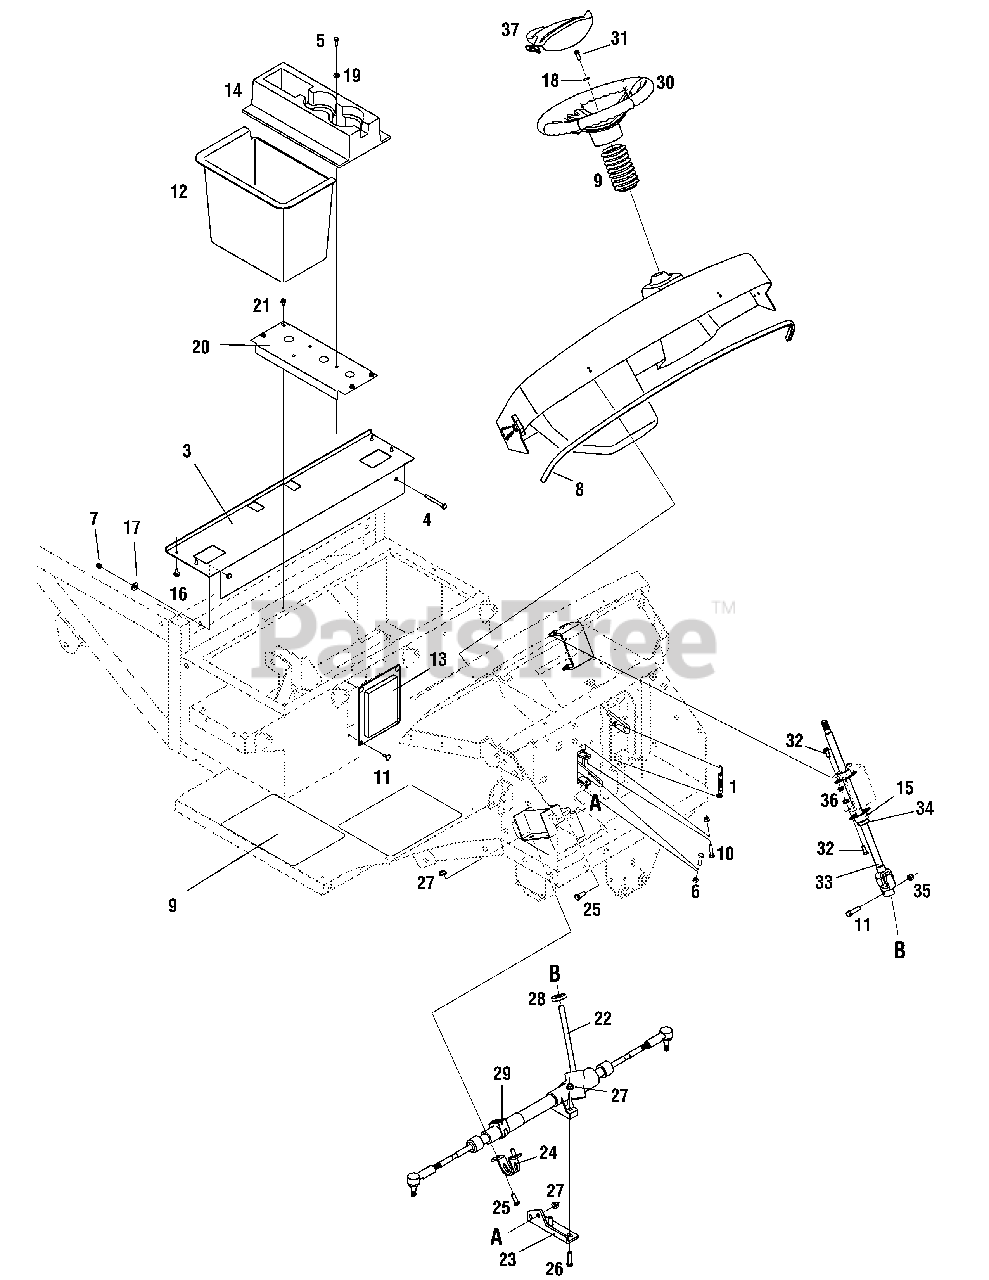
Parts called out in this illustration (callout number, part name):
1	Spring, Ext., .50 OD x 4.35 Lg.
2	Hood Mounting Plate
5	Tt Screw, 5/16-18 x .500
6	Nut, Hex, 5/16-18
7	Hex Lock Nut, Nylon, 5/16-18
8	Trim, Bulb Seal, 1/4
9	Bellow, Steering, 4.75 Lg
10	Screw, 5/16-18 x 1.25
11	Hex Screw, 3/8-16, 1.75, Gr5
12	Container, Bulkhead
13	Panel, Shift Cover
14	Console, Cup Holder
15	Brg, Flange, .75 ID, Self-Aligning
16	Bumper, Rubber
17	Washer, Flat, .349 x .879 x .063
18	Washer, Flat, .344 x .688 x .065
19	Washer, Flat, .39 x 1.38 x .062
22	Gear Assembly, Steering
25	Hex Screw, 3/8-16, 1.00, Gr8
26	Hex Screw, 3/8-16, 1.50, Gr5
27	Nut, Flange Lock, 3/8-16
28	Grommet, Steering Shaft
29	Bushing, Rubber
30	Wheel, Steering
31	Hex Scr, 5/16-18, .75, Gr5, Patch
32	Hex Screw, 5/16-18, .75, Gr5
33	Shaft, Steering, 5/8 Spline
34	Collar, .75
35	Nut, Hex Lock Nylon, 3/8-16
36	Nut, Flange Lock, 5/16-18
37	Cover, Steering Wheel
